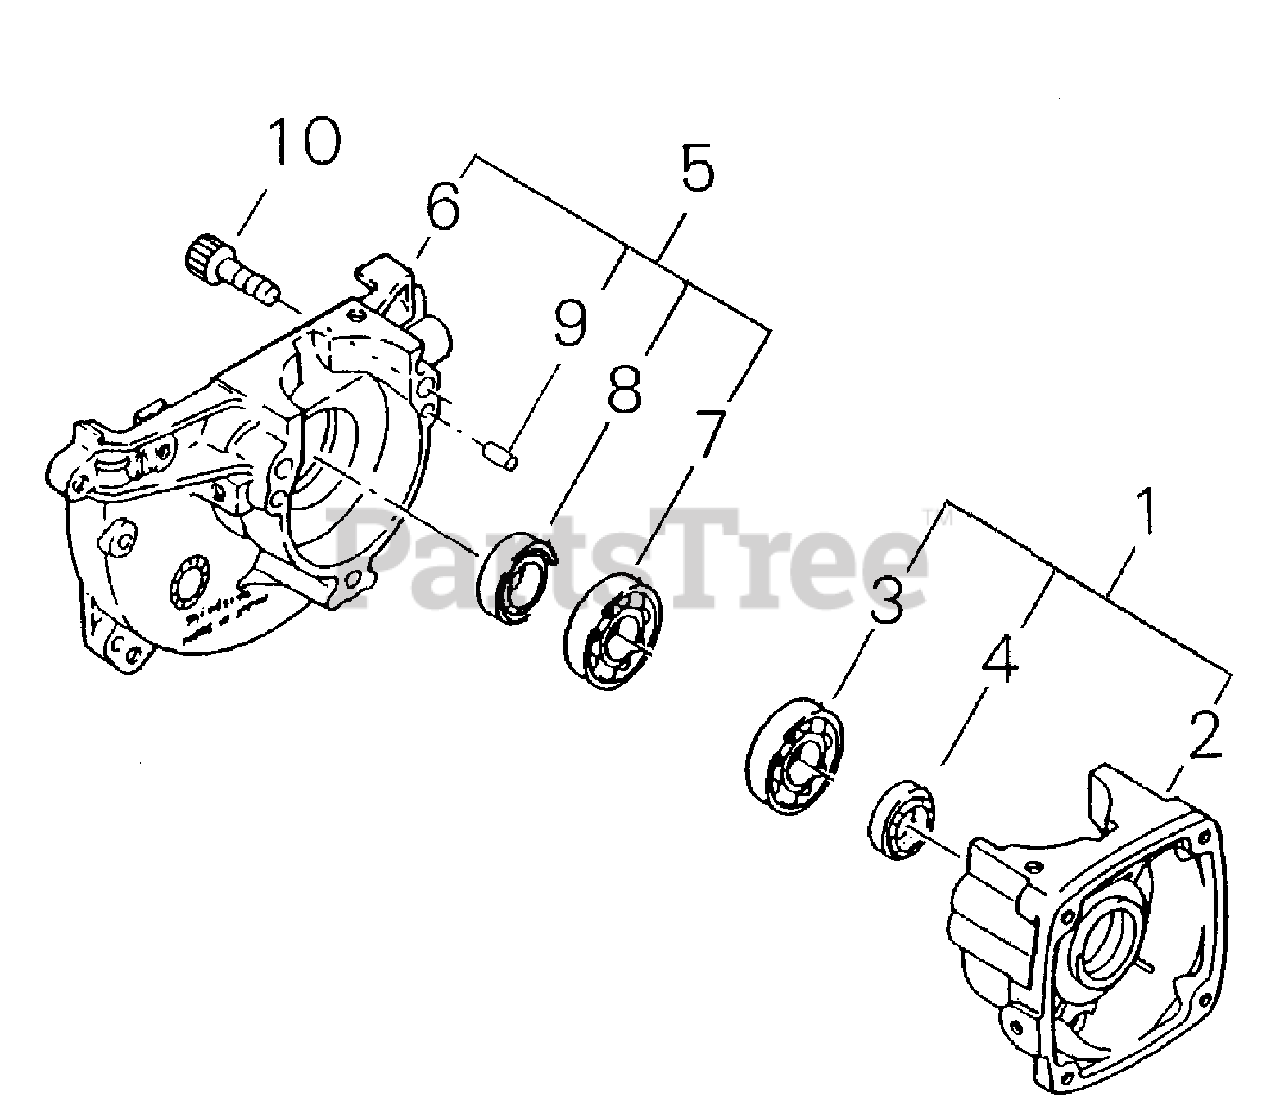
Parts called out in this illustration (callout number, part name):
2	CRANKCASE S
2-1	CRANKCASE ASSY, S
3	BEARING, BALL 6001 C3
4	SEAL, OIL 12
5	CRANKCASE ASSY, M
6	CRANKCASE M
7	BEARING, BALL 6001 C3
8	SEAL, OIL 12
9	PIN, LOCATING Ø4×8
10	BOLT 5×25
